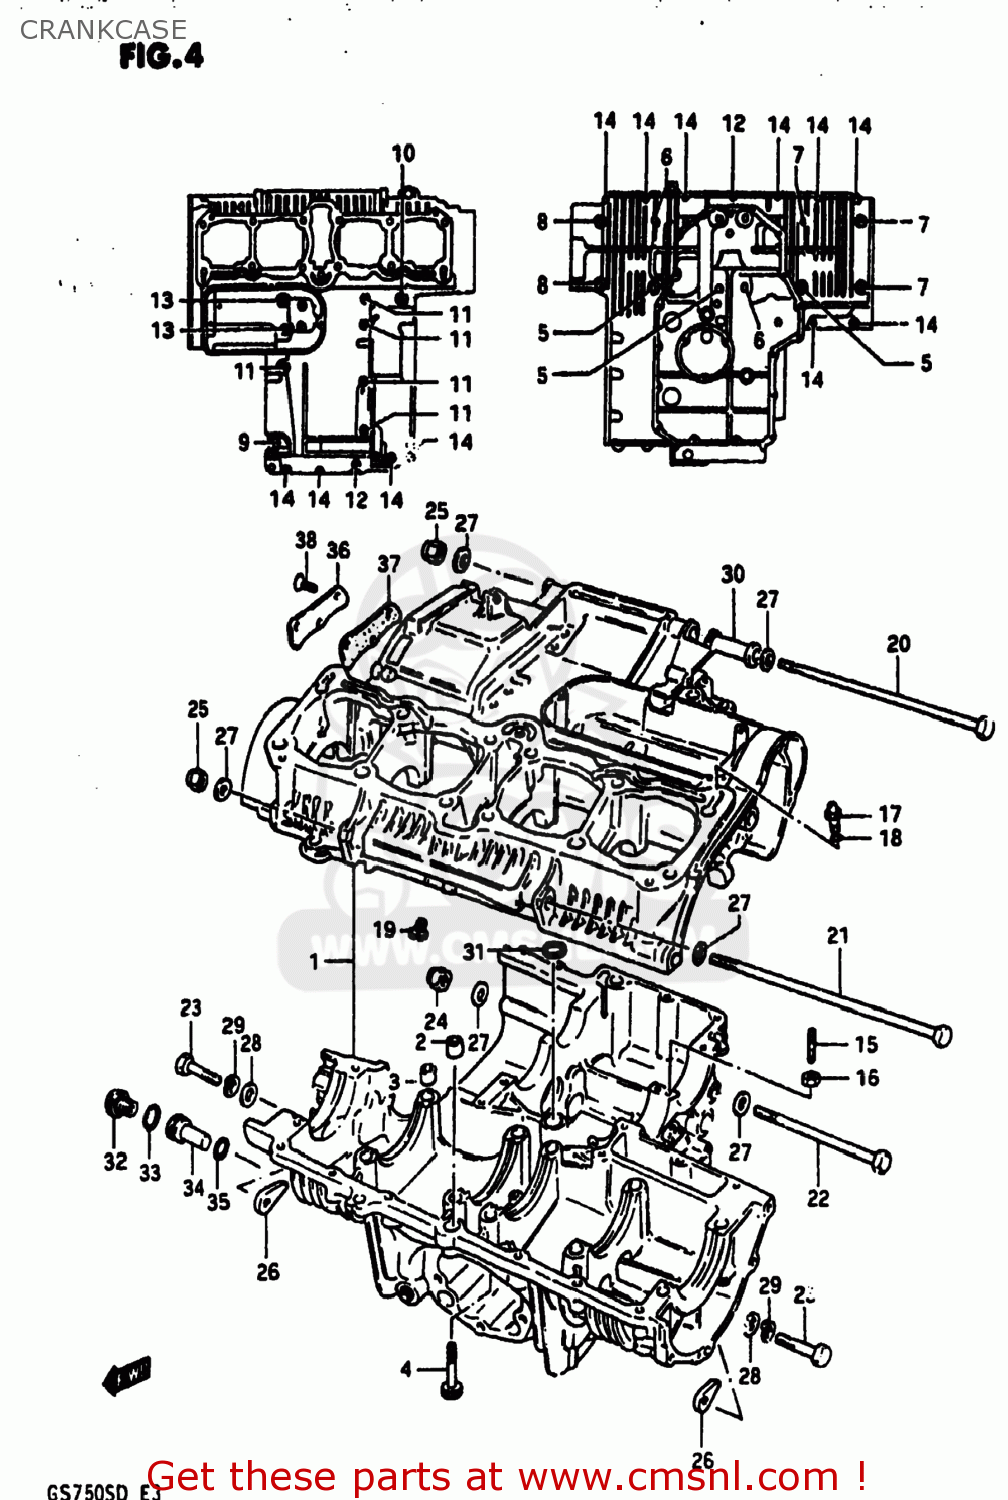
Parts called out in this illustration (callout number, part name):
1	CRANKCASE SET
2	PIN(10.4X13X22)
3	PIN (11X20)(SUS)
4	BOLT
5	BOLT(8X140)
6	BOLT
7	BOLT (8X95)
8	BOLT (8X70)
9	BOLT (8X65)
10	BOLT (5X95)
11	BOLT
12	BOLT ,6X60
13	BOLT,UNDER
14	BOLT (6X40)
15	STUD BOLT
16	NUT
17	JET
18	O RING(D:1.05,ID:3.1)
19	JET,AIR
20	BOLT(10X225)
21	BOLT(10X250)
22	BOLT(10X165)
23	BOLT 10X60
24	NUT
25	NUT
26	NUT
27	WASHER
28	WASHER (10.5X20X3.2)
29	LOCK WASHER
30	SPACER
31	O RING(D:3.2,ID:12.9)
32	PLUG
33	O RING(D:2.4,ID:17.8)
34	PIN,OIL GALLERY
35	SEAL (D:1.9 ID:9.8)
36	CAP,OIL GALLERY
37	GASKET,OIL GALLERY (MCA)
38	SCREW
